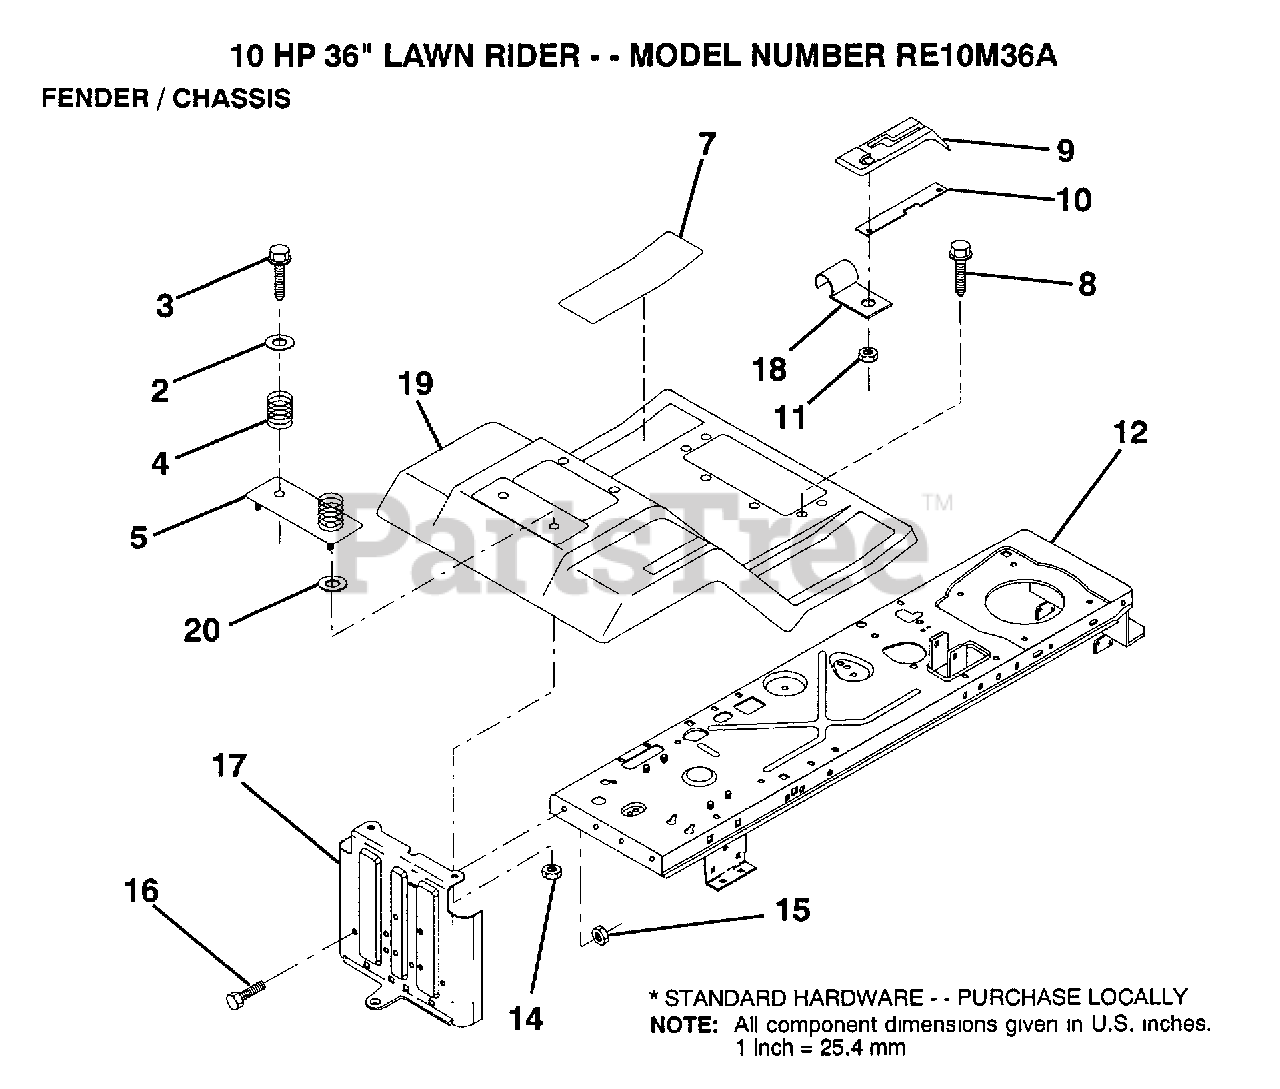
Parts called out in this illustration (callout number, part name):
2	WASHER
3	SCREW
4	SPRING COMPRESSIO
5	"PLATE, BATTERY"
7	PAD FOOTREST
8	SCREW
9	CONSOLE SHFT 4SP
11	NUT
14	NUT
16	BOLT
17	DRAWBAR
18	"CLIP,INSULATOR"
